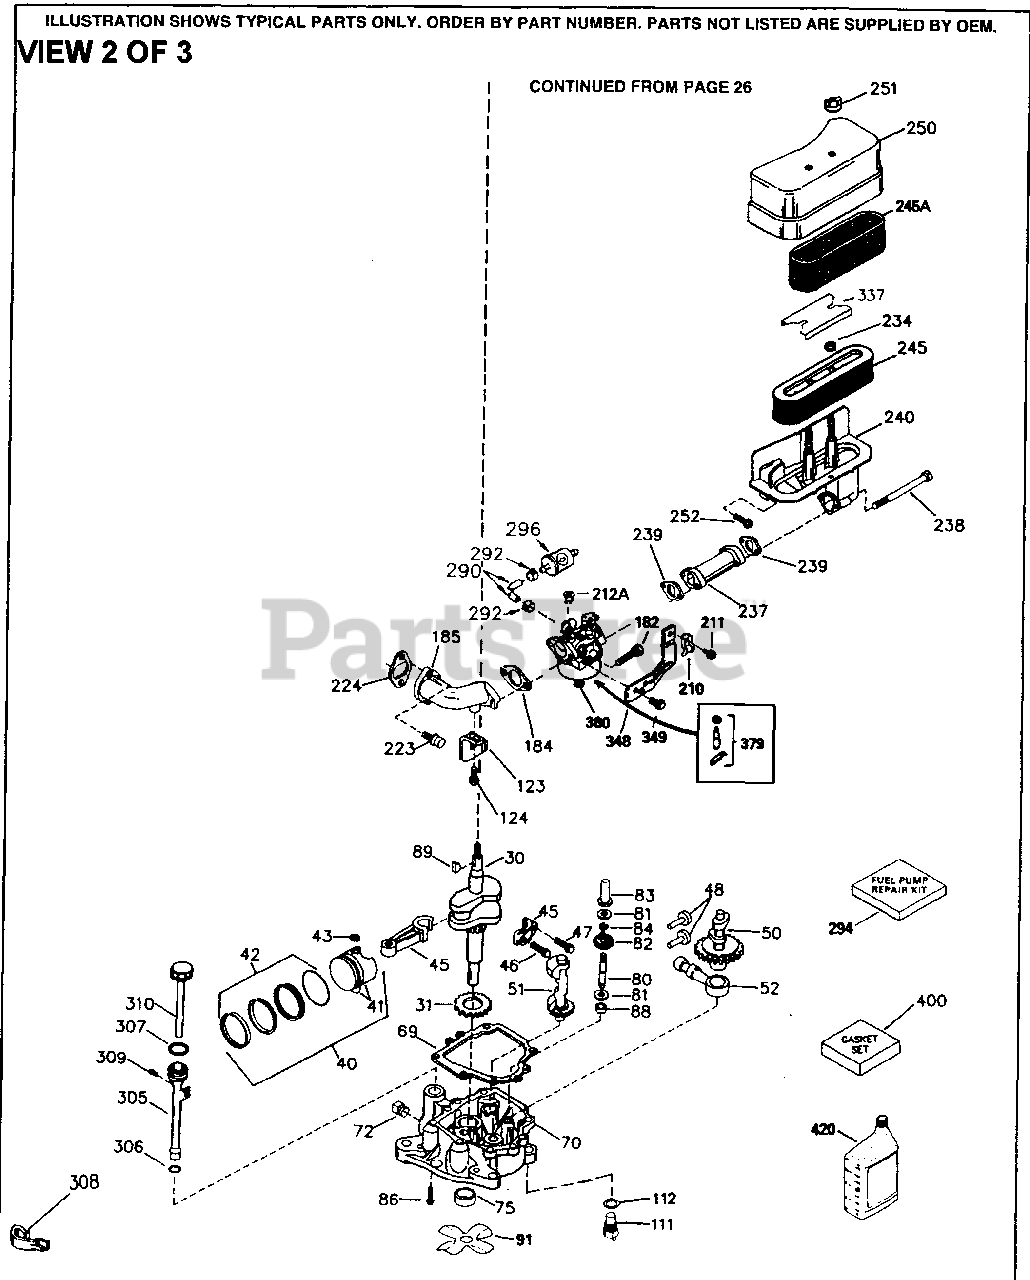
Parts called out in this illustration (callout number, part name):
30	Crankshaft
31	Counterbalance Gear
40	Piston, Pin & Ring Set (Std.)
40	Piston, Pin & Ring Set (.010" OS)
40	Piston, Pin & Ring Set (.020" OS)
41	Piston & Pin Ass'y. (Std.) (Incl. 43)
41	Piston & Pin Ass'y. (.010" OS) Incl. 43
41	Piston & Pin Ass'y. (.020" OS) Incl. 43
42	Ring Set (Std.) (3-5/16")
42	Ring Set (.010" OS)
42	Ring Set (.020" OS)
43	Piston Pin Retaining Ring
45	Connecting Rod Ass'y. (Incl. 46 & 47)
46	Connecting Rod Bolt
47	Connecting Rod Bolt
48	Valve Lifter
50	Camshaft (MCR)
51	Counterbalance Weight
52	Oil Pump Ass'y.
69	* Mounting Flange Gasket
70	Mounting Flange (Incl. 72, 72A, 75 & 80)
72	Oil Drain Plug
75	Oil Seal
80	Governor Shaft
81	WASHER
82	Governor Gear Assembly
83	Governor Spool
84	Retaining Ring
86	Screw, 1/4-20 x 1-3/16"
89	Flywheel Key
123	Intake Pipe Brace
124	Screw, 1/4-20 x 5/8"
182	Screw, 1/4-20 x 27/32"
184	* Carburetor To Intake Pipe Gasket
185	Intake Pipe
210	Conduit Clip
211	Screw, 10-32 x 3/8"
212A	Bushing
223	Screw, Torx T-30, 5/16-18 x 7/8"
224	* Intake Pipe Gasket
234	Nut & Lockwasher, 1/4-20
237	Air Filter Adapter
238	Screw, 10-32 x 5-1/4"
239	* Carburetor Gasket
240	Air Cleaner Body (Incl. 239)
245	Air Filter (Incl. 234) also available in Packaged Part #740015B
245A	Pre-Cleaner Air Filter also available in Packaged Part #740015B
250	Air Cleaner Cover
251	Wing Nut, 1/4-20
290	Fuel Line (8.62")
292	Fuel Line Clamp
296	Fuel Filter (Incl. 292) also availabl e as Packaged Part #740003B
305	Oil Fill Tube
307	"O" Ring
308	Fill Tube Clip
310	Dipstick
323B	Terminal
337	Deflector
380	Carburetor (Incl. 184)
400	* Gasket Set (Incl. items marked PK in notes) Incl. part #'s 27896 (2),33263 (1), 33629 (2), 34265 (1),35317 (1), 35762 (2), 35946 (1),35952 (1), 3595 8 (1)
